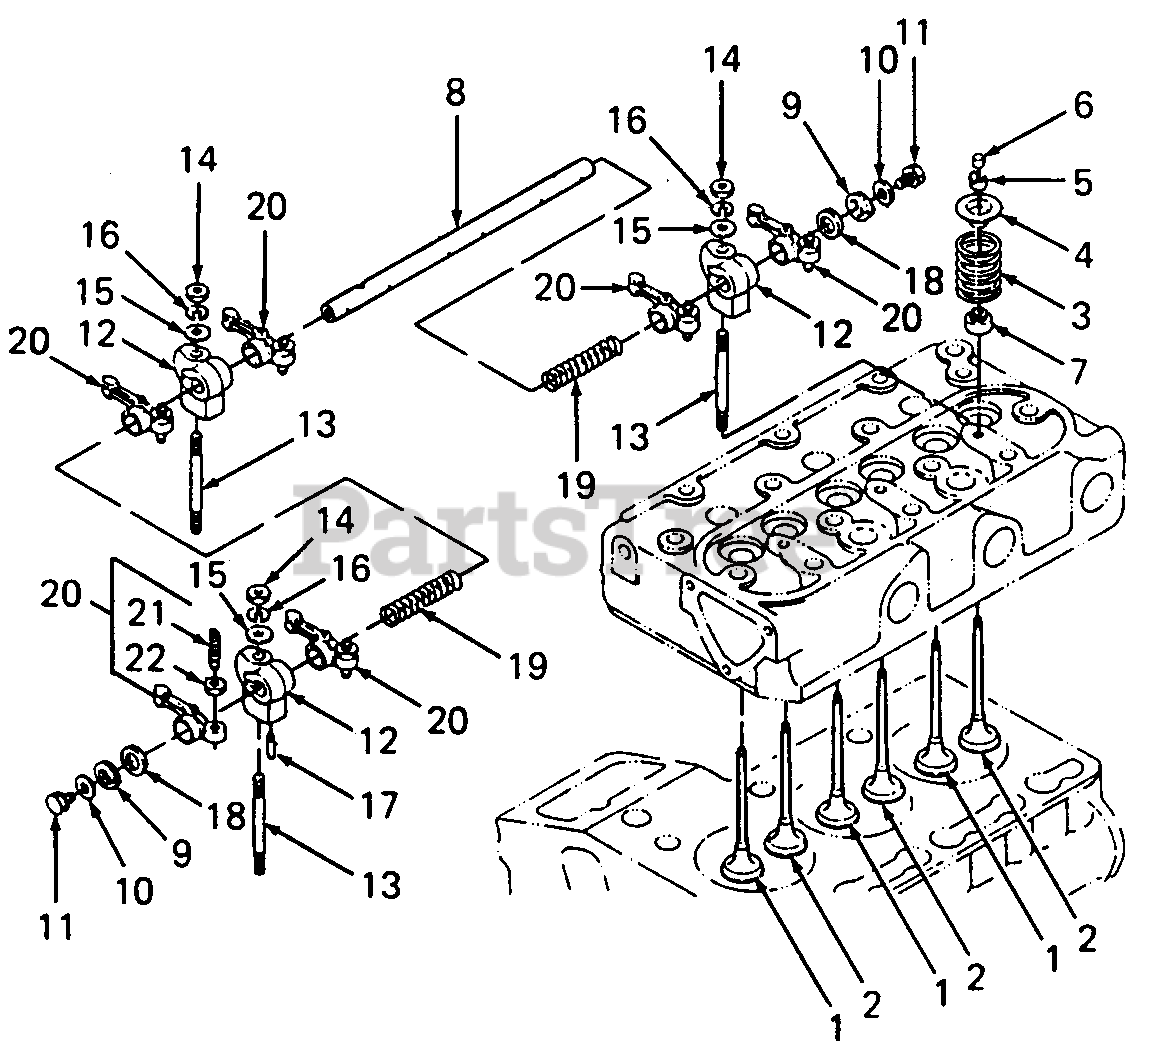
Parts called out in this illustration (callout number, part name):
2	Valve, Exhaust
3	Spring, Valve
4	Retainer, Valve Spring
5	Collet, Valve Spring
7	Seal, Valve Stem
8	Shaft, Rocker Arm
9	Spring, Thrust
10	Washer, Plain
12	Bracket, Rocker Arm
15	Washer, Plain
16	Washer, Spring
19	Spring, Rocker Arm
20	Rocker Arm Assy
21	Screw, Adjusting
